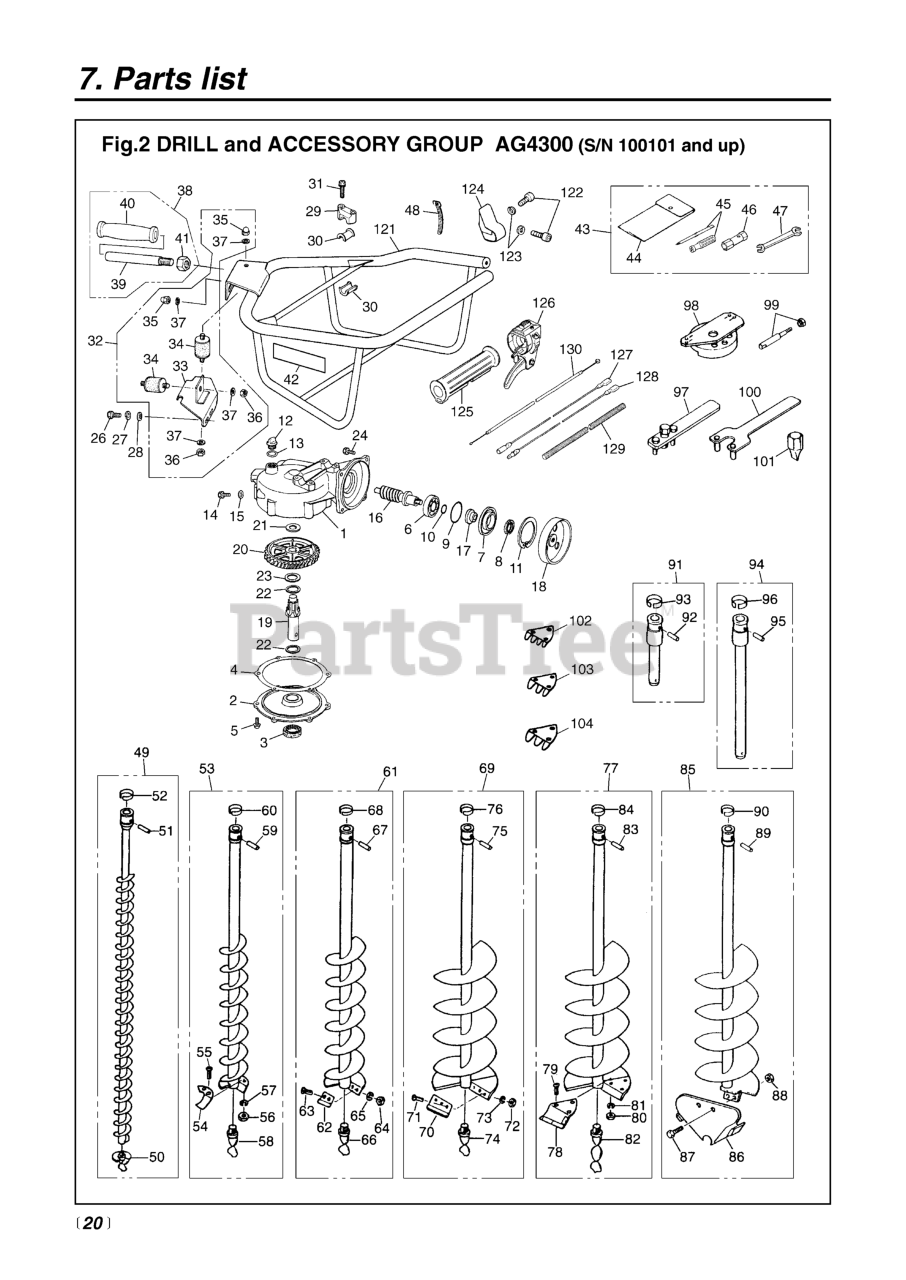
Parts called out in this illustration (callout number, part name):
1	GEARCASE COMP (RPLS -11102)
2	COVER COMP (RPLS -11202)
3	SEAL, OIL
4	GASKET
7	RETAINER
9	O-RING
11	RING, SNAP, M62 x 2.0
19	SHAFT
24	BOLT, M6 x 20
28	WASHER, M6 X 2.3
30	SPACER
31	BOLT, M6 x 30
32	BRACKET ASSY (RPLS-31201)
36	NUT, M6 X 5
37	WASHER, M6 X 15
38	HANDLE COMPLETE
39	HANDLE-L
41	NUT, M14 x 11
42	NAME PLATE
43	TOOL SET
45	SCREWDRIVER
47	SPANNER, 8 X 10 (RPLS 2540- )
48	BAND
49	S40 DRILL ASS
51	PIN
52	CLIP
53	DRILL S60 ASS
55	SCREW, M6 X 20
56	NUT, M6 X 5
57	WASHER, M6 X 15
58	BIT
59	PIN
60	CLIP
61	S90 DRILL ASS
62	TIP, S90
63	SCREW, M6 X 20
64	NUT, M6 X 5
65	WASHER, M6 X 15
66	BIT
67	PIN
68	CLIP
69	S150 DRILL ASS
70	TIP, S150
71	SCREW, M6 X 20
72	NUT, M6 X 5
73	WASHER, M6 X 15
74	BIT
75	PIN
76	CLIP
77	S200 DRILL ASS
78	TIP, S200
79	SCREW, M6 X 20
80	NUT, M6 X 5
81	WASHER, M6 X 15
82	BIT
83	PIN
84	CLIP
85	I150 DRILL ASS
87	BOLT, M6 x 20
88	NUT, M6 X 5
89	PIN
90	CLIP
91	JOINT L100 ASS
92	PIN
93	CLIP
94	JOINT L300 ASS
95	PIN
96	CLIP
98	SET BLOCK (TOOL)
99	ROD ASSEMBLY (TOOL)
121	FRAME
124	BRACKET, FRAME
125	GRIP (RPLS 3577-32140 & 3220-
126	LEVER
127	CORD
129	TUBE
130	CABLE COMP.
